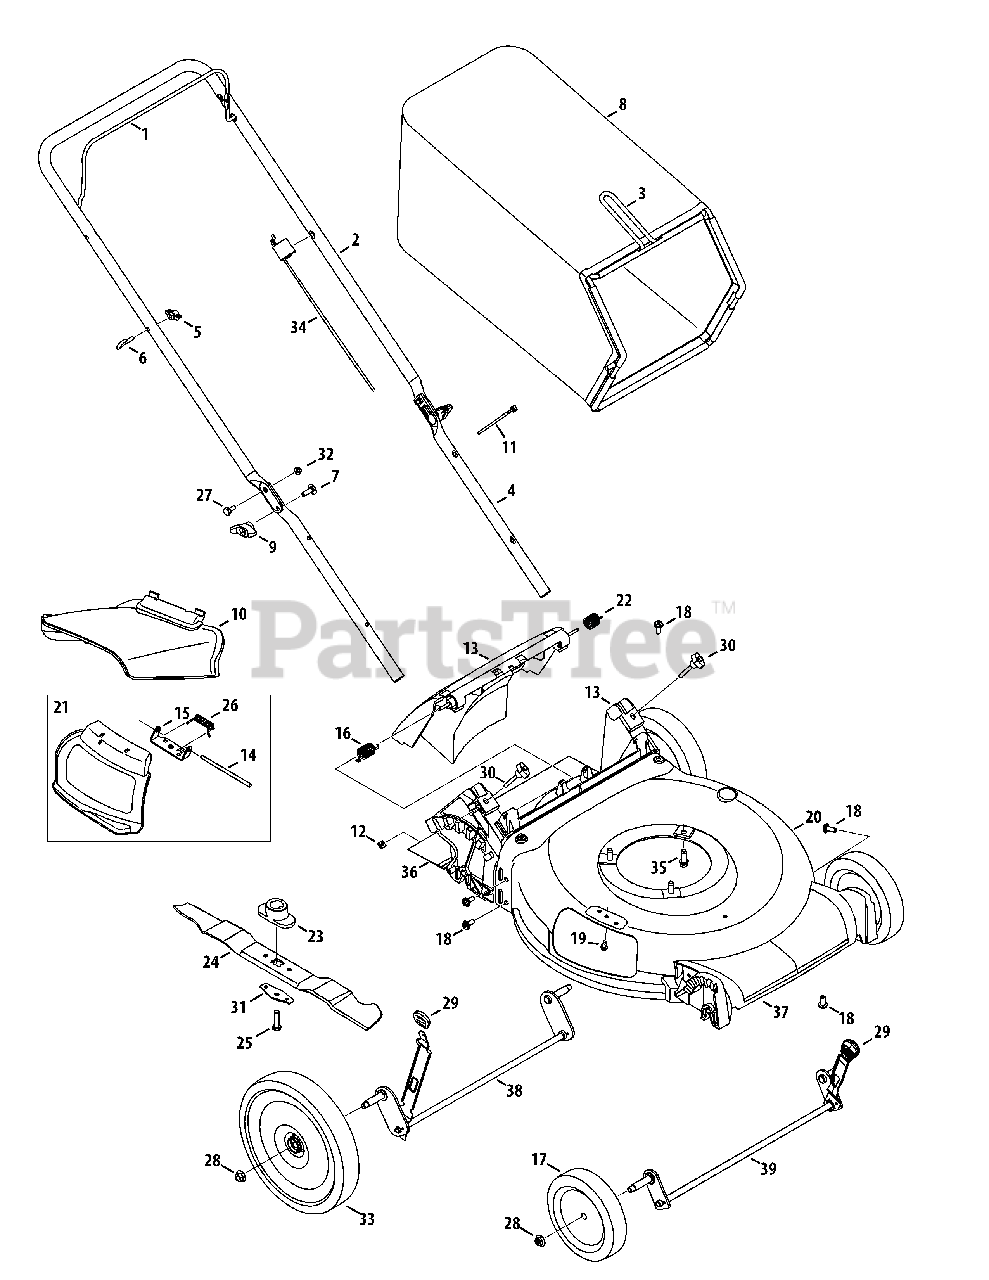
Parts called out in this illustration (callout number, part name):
1	Blade Control, Standard
2	Upper Handle
3	Grass Catcher Frame
4	Lower Handle
5	Wing Nut
6	Rope Guide
7	Carriage Screw ,5/16-18
8	Grass Bag
9	Wing Knob
10	Side Chute
11	Cable Tie
12	Nut, Sq., 1/4-20
13	Rear Discharge Door Assembly
14	Hinge Pin
15	Chute Deflector Bracket
16	Torsion Spring - RH
17	Font Wheel Gray
18	Screw, 5/16-14 x .750
19	Screw, 1/4-20 x .500
20	Deck , 21"
21	Hinged Mulch Plug Assembly
22	Torsion Spring - LH
23	Blade Adapter, 25mm x 1.19
24	Mulching Blade
25	Screw , 3/8-24 x 1.50
26	Torsion Spring
27	Sldr. Screw, .375 x .126 x 1/4-20
28	Flange Lock Nut, 3/8-16
29	Adjustment Lever Knob
30	Wing Nut
31	Blade Bell Support
32	Nut, Flange Lock, 1/4-20
33	Rear Wheel Gray
34	Control Cable, 37.58"
35	TT Sems Screw, 3/8-16 x 1.0
36	Trail shield
37	Front Cover
38	Rear Axle Assembly
39	Front Axle Assembly
